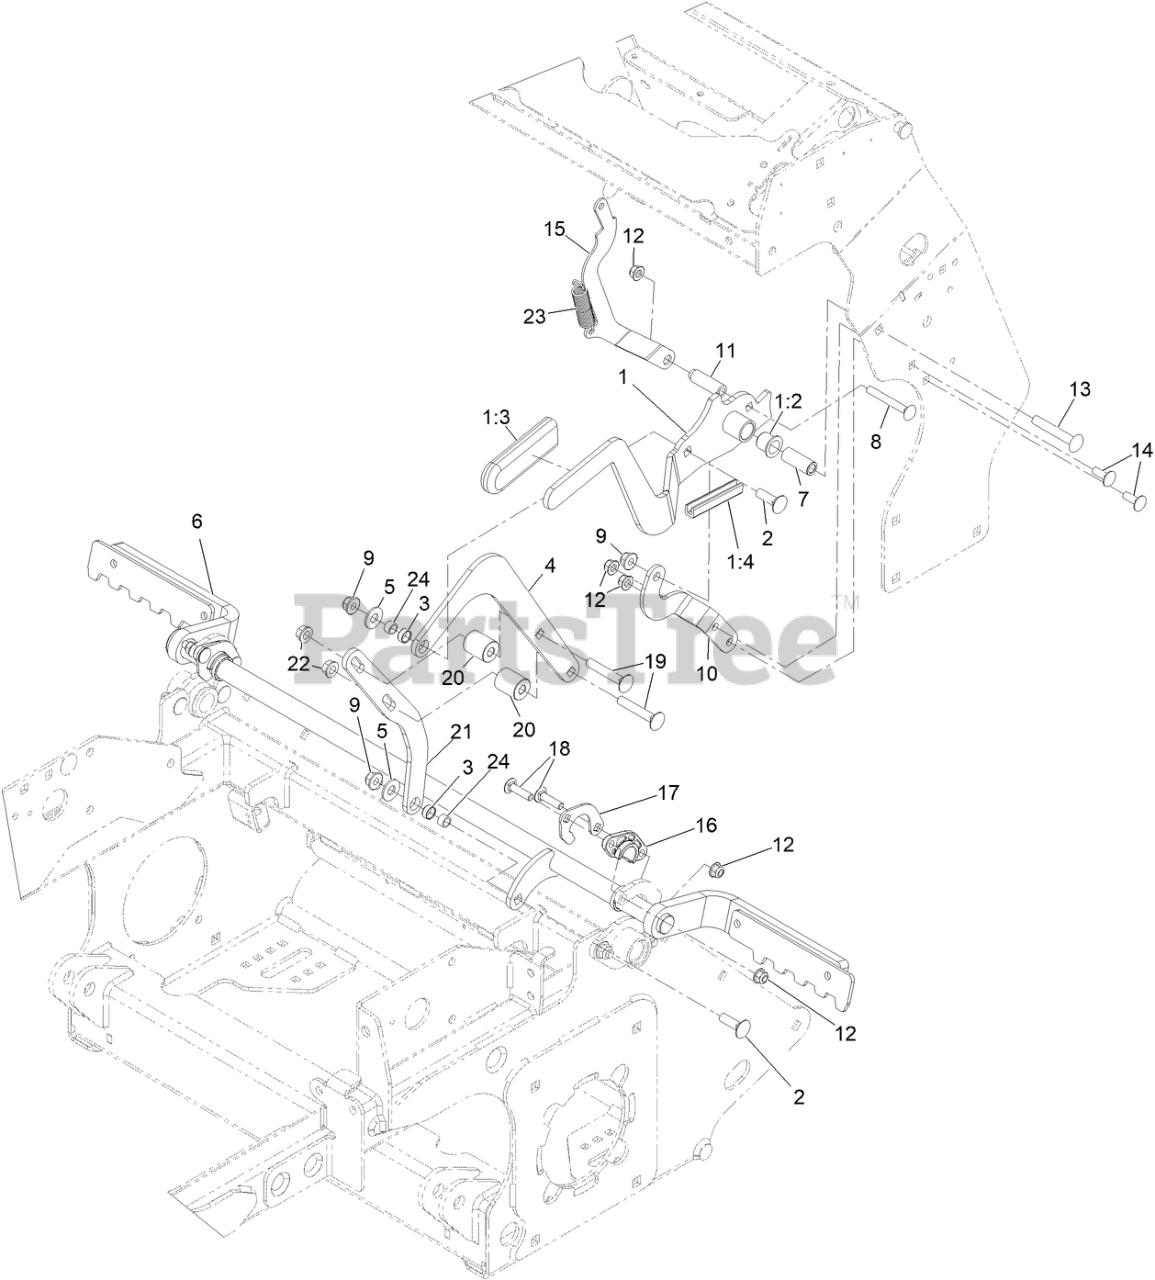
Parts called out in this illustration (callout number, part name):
1	ASM-HANDLE BRAKE
1:2	BUSHING-FLANGE
1:3	GRIP-LEVER
1:4	Trim - Edge
2	BOLT-CARR
3	BEARING-SLEEVE
4	LINK-BRAKE UPPER
5	WASHER-FLAT
6	ASM-Brake Shaft [black]
7	SPACER-PIVOT
8	SCREW-CARR
9	NUT-HF, NI
10	Bracket-Brake Lever Supt
11	SPACER-.31 X 1.25 YZ
12	NUT-HF, NI
13	SCREW-CARR
14	BOLT-CARR
15	Link-Brake Control Lock
16	BUSHING-FLANGE
17	SUPPORT, BEARING
18	SCREW-CARR
19	Bolt-Carriage 3/8-16 X 2 1/4
20	SPACER-.39 IDX1.0 ODX1.2 L
21	LINK-BRAKE LOWER
22	NUT-HHF, WHIZ
23	SPRING-EXTENSION
24	SPACER-BRAKE PIVOT
